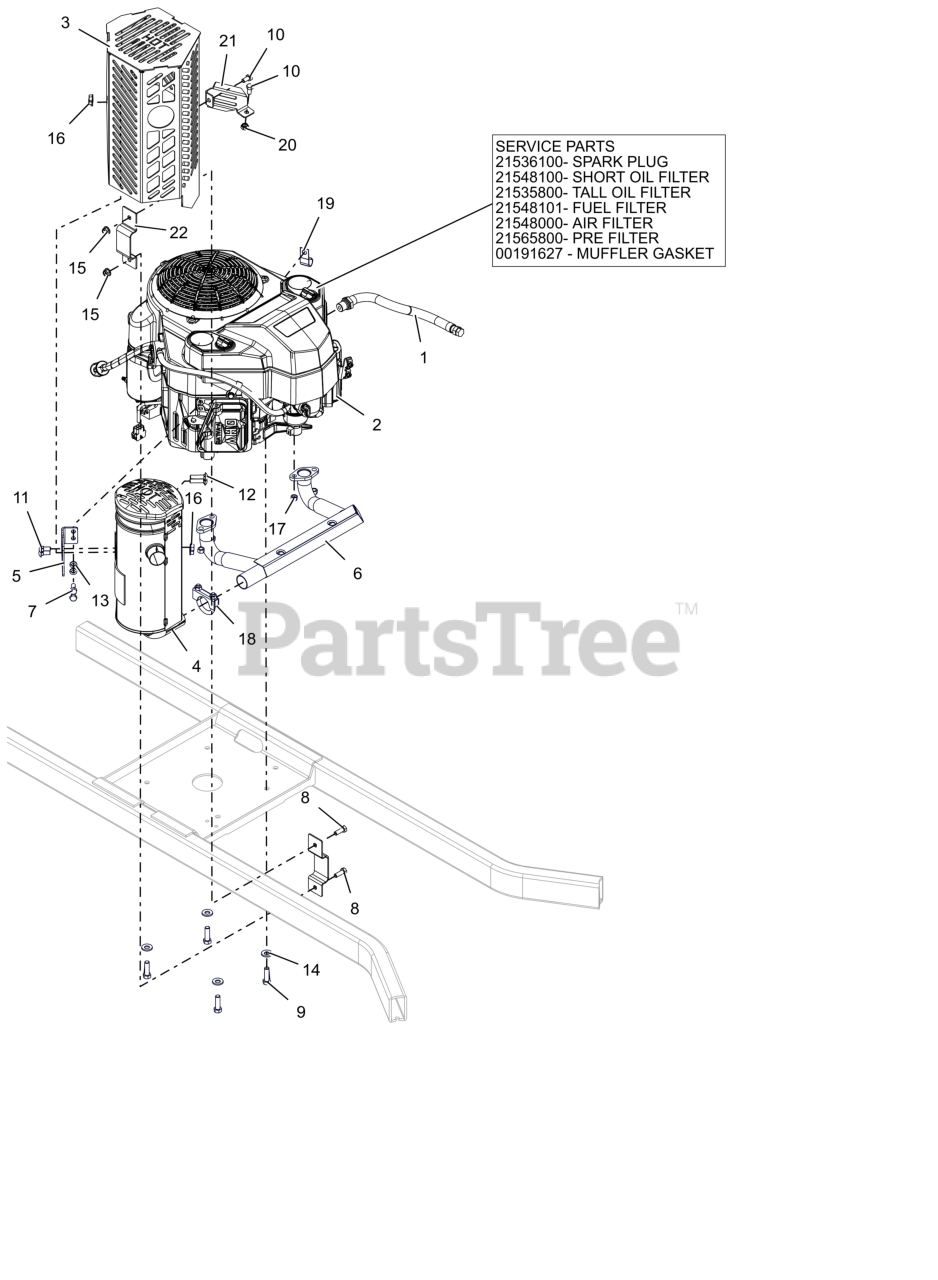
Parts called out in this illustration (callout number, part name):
1	HOSE, OIL DRAIN
2	ENGINE, KAWASAKI FS600V
2	PLUG, SPARK
2	OIL FILTER, KAWASAKI FR
2	FILTER,OIL - KAW
2	FUEL FILTER-KAWASAKI FR
2	AIR FILTER, KAWASAKI FR
2	PRE FILTER- KAWASAKI FS
2	GASKET, MUFFLER S/O
3	WLDMT, EXHAUST MUFFLER GUARD (BLACK)
4	MUFFLER, PROSTANCE
5	BRKT, MFLR MOUNT (BLACK)
6	MANIFOLD PRO STANCE 32-36" EXHAUST
7	BLT, HEX M8-1.25X20 G8.8 ZCC
8	BLT, HEX .31-18X.875 G5 ZCC
9	BLT, HEX .38-16X1.25 G5 ZCC NT
10	BLT, HEX .31-18X.625 G5 ZCC
11	BLT,RHSN .31-18X.75 G5 ZCC
12	BLT, RHSSN.31-18X1.25 G5 ZCC
13	WSHR,LK-REG .312X.078 ZCC
14	WASHER, 3/8" SPRING DISC
15	NUT,LK-NYL-FLG .31-18 G5ZC120
16	NUT,LK-CTR-FLG .31-18 GF ZCC
17	NUT-LK-TOP-FLG M8 ZCC
18	CLAMP, MUFFLER - 1.438
19	J-CLAMP
20	NUT-WELD .31-18
21	BRKT, EXHAUST MUFFLER GUARD
22	CHASSIS, BRKT EXHAUST MUFFLER COVER
